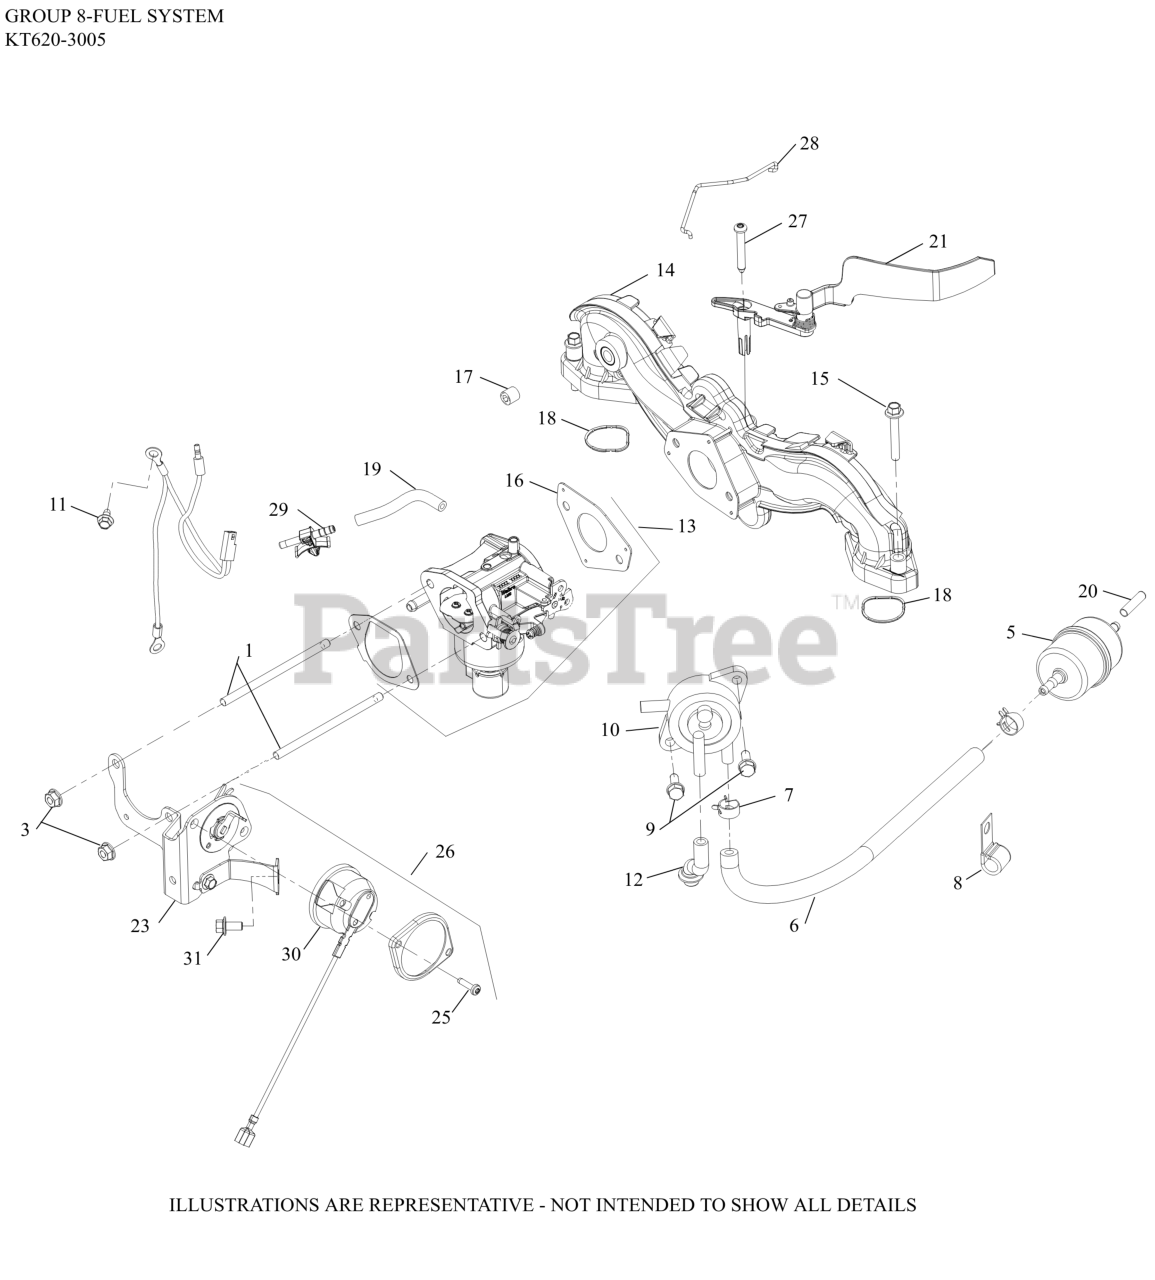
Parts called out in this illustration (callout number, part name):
3	NUT, FLG M6X1.0
5	FILTER, FUEL
6	HOSE,LW PERM.FUEL 24.00"-USE 25 111 81-S
7	SPRING CLAMP, HOSE
8	CLIP, CABLE
9	SCREW, TAP M6X1.7X18
10	PUMP, FUEL (PULSE)-(#2539326S)
11	SCREW, THREAD FORMING
12	HOSE, PULSE PUMP(STEEL COVERS)
13	KIT,CARB(WALBRO)
14	KIT, INTAKE MANIFOLD-(#24164277S)
15	SCREW, FLG M6X1.0X40
16	GASKET, CARBURETOR
17	PLUG, CTSK PIPE 1/8"
18	O-RING, INTAKE PORT (PIM)
19	HOSE EVAPORATIVE (WALBRO)
20	CAP, MASKING
21	DEFLECTOR ASSEMBLY, AIR VANE
23	BRACKET ASSY, AUTO-CHOKE (MECH)
25	SCREW, PAN HEAD THREAD FORMING (M4)
26	THERMOSTAT ASSY (CDI) - USE 32 755 27-S
27	SCREW, PAN HEAD (#12-14 X 38 MM)
28	LINKAGE, CHOKE UPLOADER
29	CONNECTOR, EVAPORATIVE
30	KIT, THERMOSTAT, ELECTRIC CHOKE
31	SCREW, FLG M6X1.0X12
NI	KIT,REPAIR OVERHAUL(WALBRO)
NI	KIT,BOWL O-RING(WALBRO)
NI	KIT, HI ALTITUDE (5000 FT) 19MM
NI	KIT,SOLENOID REPAIR(WALBRO)
NI	KIT,REPAIR FLOAT(WALBRO)
